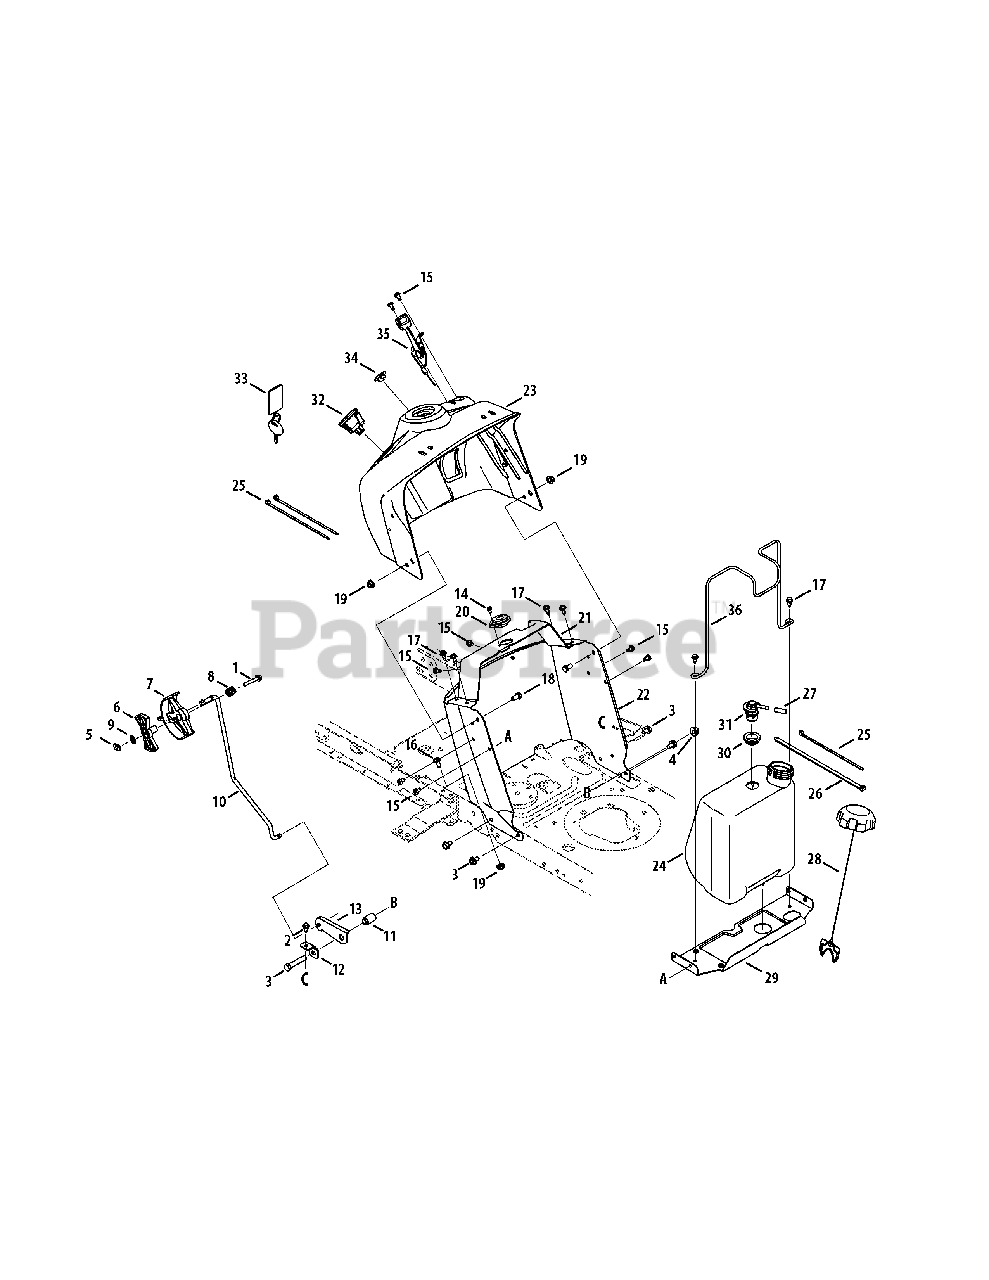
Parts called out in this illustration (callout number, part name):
1	Hex Head Screw, 1/4-20 x 1.50
2	Self-Tap Screw, 1/4-20 x .625
3	Hex Head Screw, 3/8-16 x 2.00
4	Flange Lock Nut, 3/8-16
5	Top Lock Weld Nut, 1/4-20
6	Index Control
7	Shift Lever
8	Compression Spring, .685 x .63
9	Internal Lock Washer, 1/4
10	Speed Control Rod
11	Flange Spacer, .390 x .671 x 1.095
12	Speed Latch Tab
13	Speed Latch
14	Screw, #10
15	Self-Tap Screw, 1/4-20
16	Self-Tap Screw, 5/16-18
17	Hex Washer Screw, 1/4-20 x .625
18	Hex Head Screw, 5/16-18
19	Flange Lock Nut, 5/16-18
20	Steering Column Bearing
21	Steering Support Bracket
22	Lower Dash
23	Upper Dash Panel
24	Fuel Tank
25	Cable Tie, 3/16 x 7.4"
26	Cable Tie, 36" Lg.
27	Vent Hose
28	Fuel Cap
29	Gas Tank Support Bracket
30	Rubber Grommet
31	Fuel Rollover Valve
32	Key Switch Module
33	Key Assembly
34	Choke Plug
35	Throttle/Choke Assembly
36	Fuel Tank Support Rod
